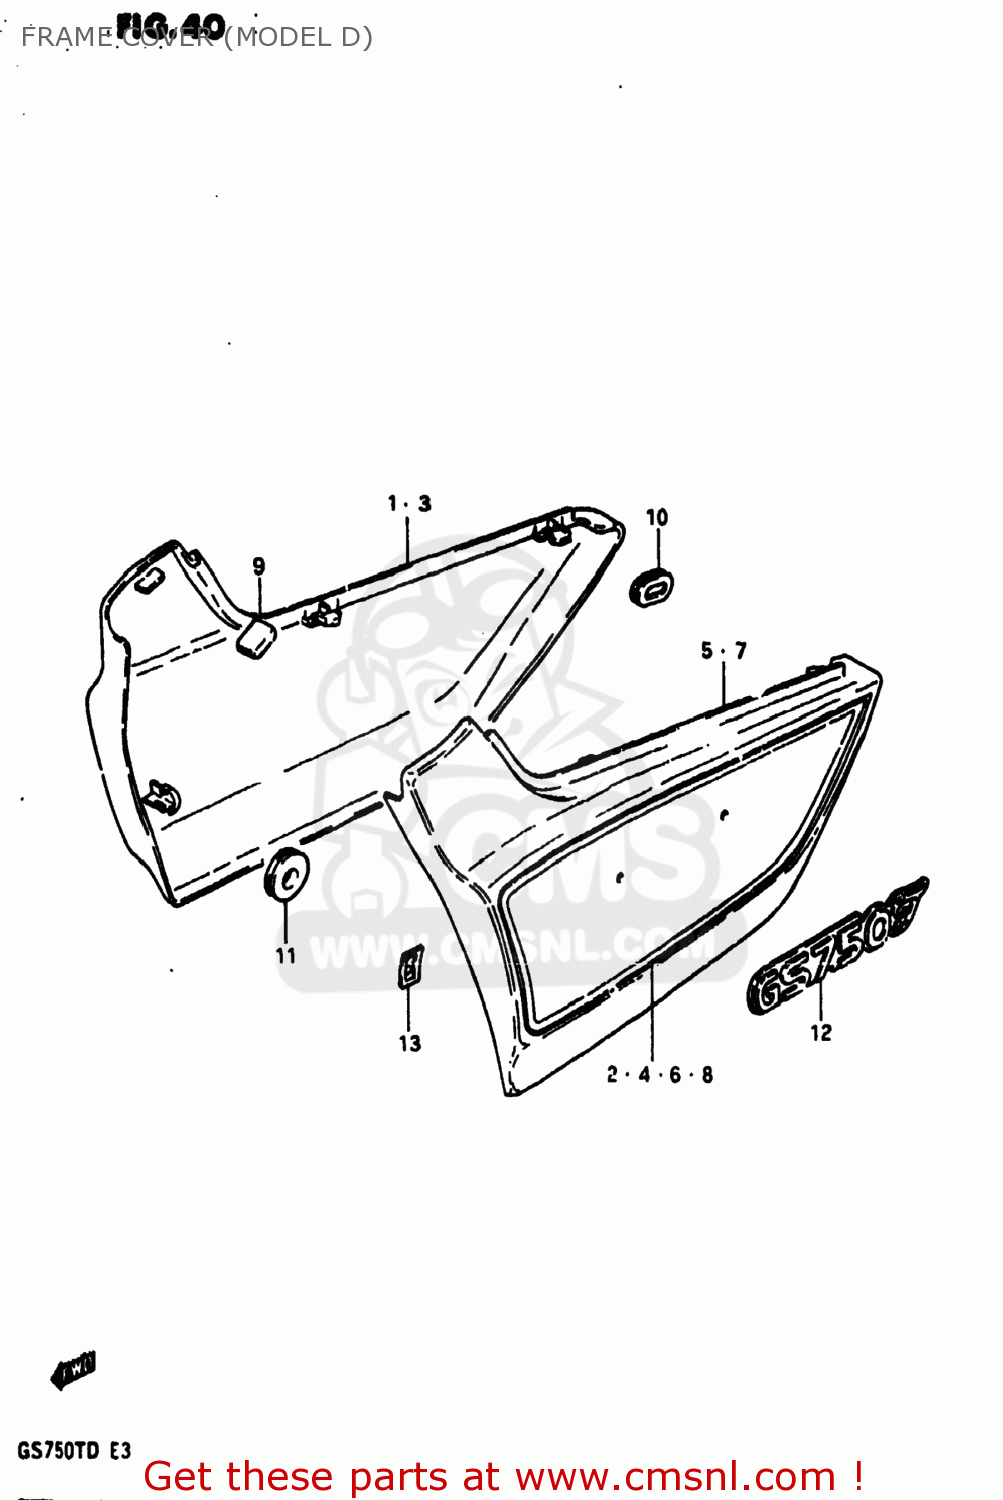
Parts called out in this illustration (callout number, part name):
1	COVER,FRAME,RIGHT
2	TAPE SET,FRAME COVER
3	COVER,FRAME,RIGHT
4	TAPE SET,FRAME COVER
5	COVER,FRAME,LEFT
6	TAPE SET,FRAME COVER
7	COVER,FRAME,LEFT
8	TAPE SET,FRAME COVER
9	CUSHION
10	CUSHION
11	CUSHION
12	EMBLEM,FRAME COVER
13	NUT
